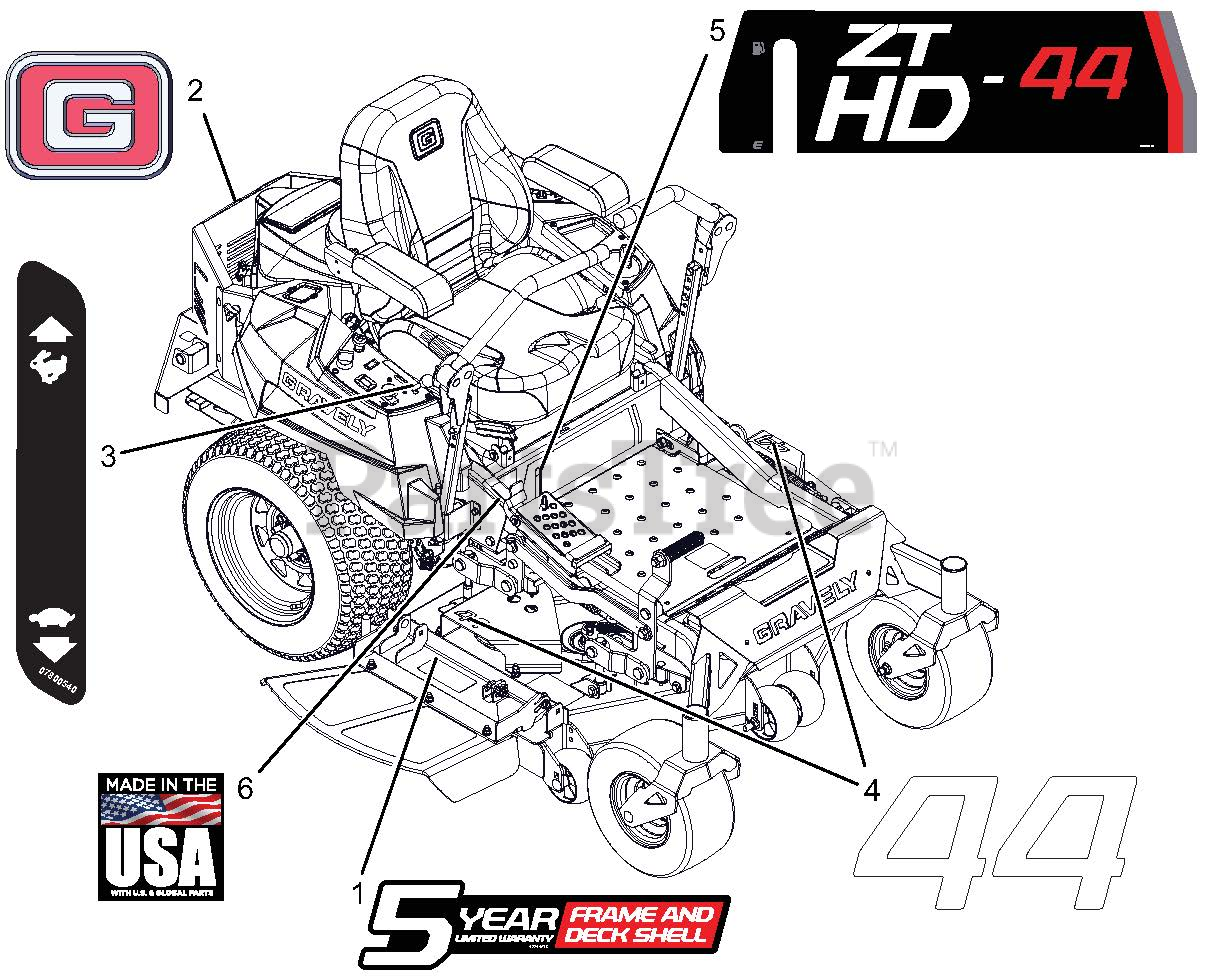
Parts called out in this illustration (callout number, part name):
1	DECAL, DECK 5 YEAR-GRAVELY
2	DECAL, GRAVELY BRAND
3	DECAL, DASH DECAL
4	DECAL - 44"
5	DECAL - 44HD
6	DECAL, MADE IN USA
